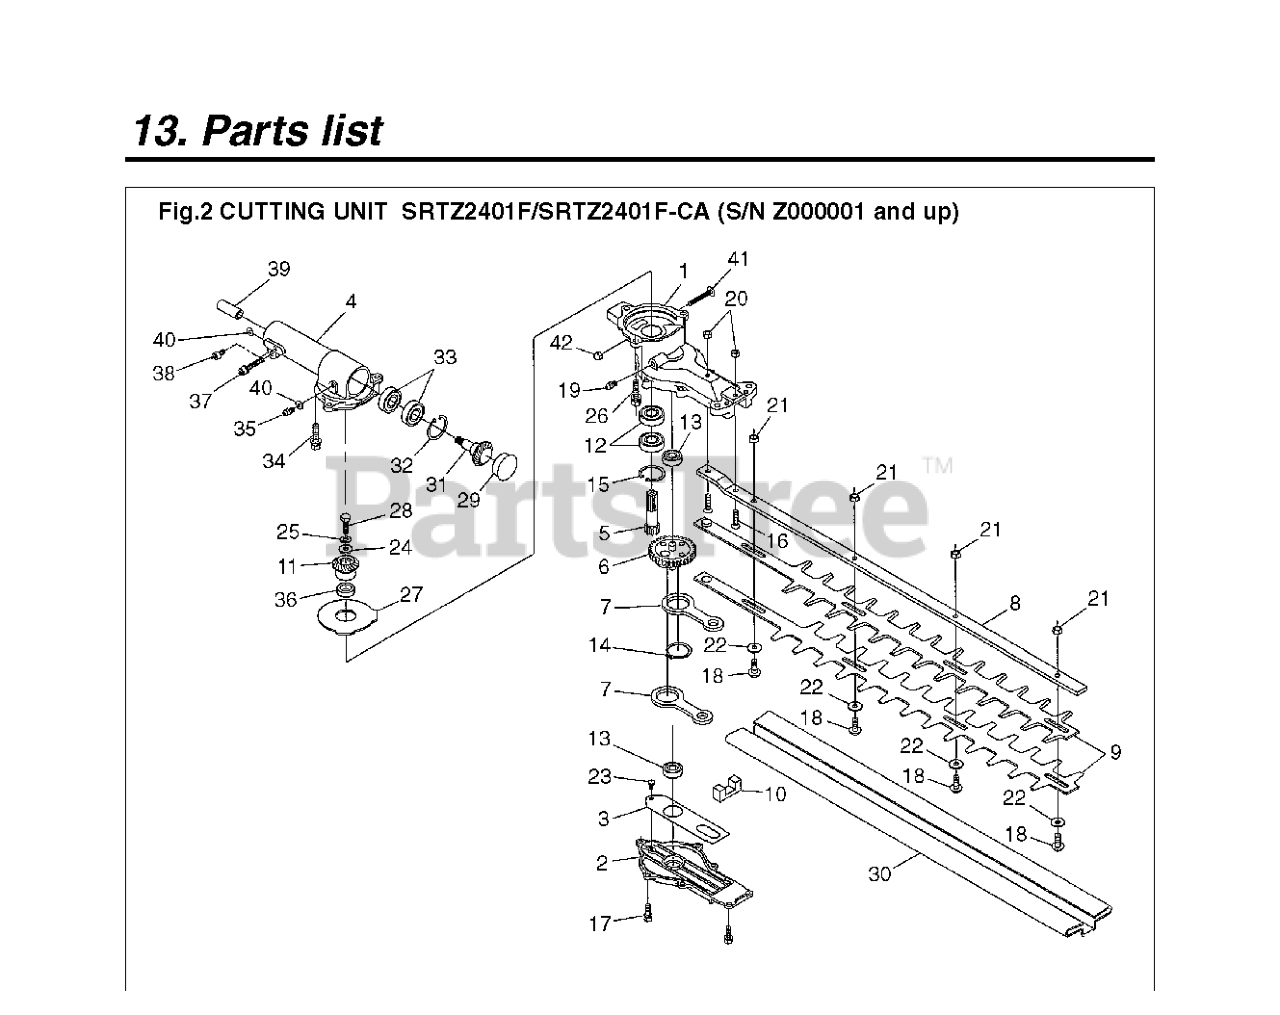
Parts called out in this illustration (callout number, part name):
1	CASING A
5	PINION GEAR
6	CRANK GEAR
8	GUIDE PLATE
11	BEVEL GEAR A
13	BEARING
14	SNAP RING
17	SCREW
18	SCREW(R3873,388411750&11770
20	U NUT M5
28	BOLT M6X20
31	BEVEL GEAR B
32	RING,SNAP M26x1.2 RP-318013340
34	BOLT M6X25
37	BOLT M5X30
38	BOLT M5X10
